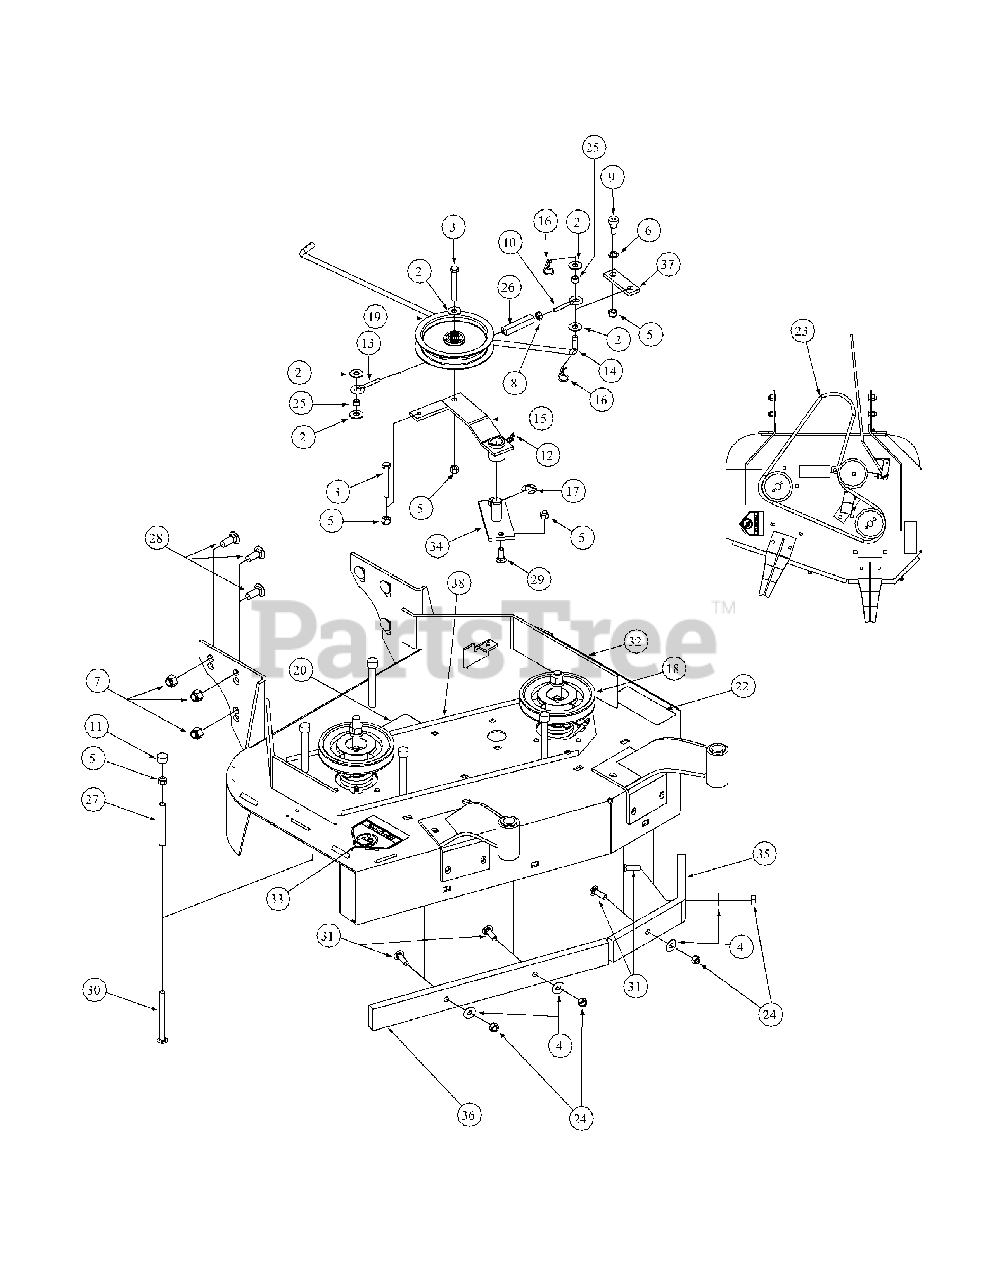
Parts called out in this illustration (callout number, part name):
2	Flat Washer, 3/8 Zinc
3	Hex Cap Screw, 3/8-16, 2.75
4	Flat Washer, 3/8 Zinc
5	Lock Nut, Nylon Insert, 3/8-16
6	Shim Washer
7	Lock Nut, Nylon Insert, 1/2-13
8	Hex Nut, 5/16-18
9	Shoulder Bolt
10	Eye Bolt, Right Hand
11	Cap, Black Vinyl
12	Grease Fitting, 1/4-28; 45°.
13	Eye Bolt, Left Hand
14	Blade Clutch, Rod
15	Idler Arm
16	Hair Pin, 3/8"-1/2"
17	E-Ring, Retainer
18	Pulley Deck
19	Idler Deck Take-up
20	Decal Rotating Blade
22	Decal, Warning Shield Missing
23	Belt Drive
24	Lock Nut, 3/8-16
25	Turnbuckle, Sleeve
26	Turnbuckle
27	Spacer, Belt Guide
28	Carriage Bolt, 1/2-13 x 1-1/4
29	Carriage Bolt, 3/8-16 x 2
30	Carriage Bolt, 3/8-16 x 4.5
31	Carriage Screw, 3/8-16 x 1.25
32	Deck 32"
33	Decal, Danger, Hands and Feet
34	Idler Base
35	Bumper, Deck 32"
36	Bumper, Deck 32"
37	Pivot Arm
38	Deck Stiffener
